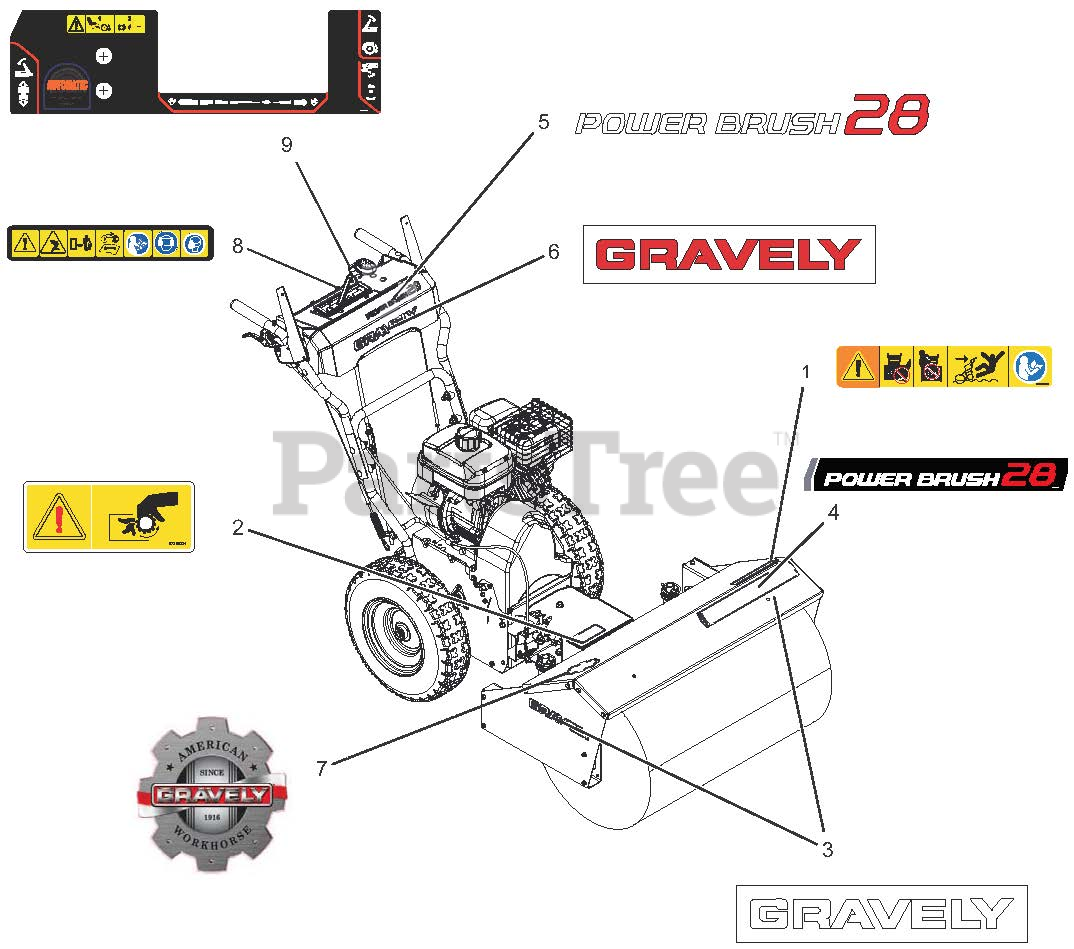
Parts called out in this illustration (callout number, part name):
1	DECAL, DANGER -POWER BRUSH-CE
2	DECAL, PTO WARNING
3	DECAL, 9.5" GRAVELY LOGO
4	DECAL,POWER BRUSH 28,GRAVELY
5	DECAL,POWER BRUSH 28,GRAVELY
6	DECAL,GRAVELY,RED,9.5"
7	DECAL, GRAVELY HERITAGE-LARGE
8	DECAL, SAFETY, DASH, BRUSH
9	DECAL,CONTROL,SMALL BRUSH
